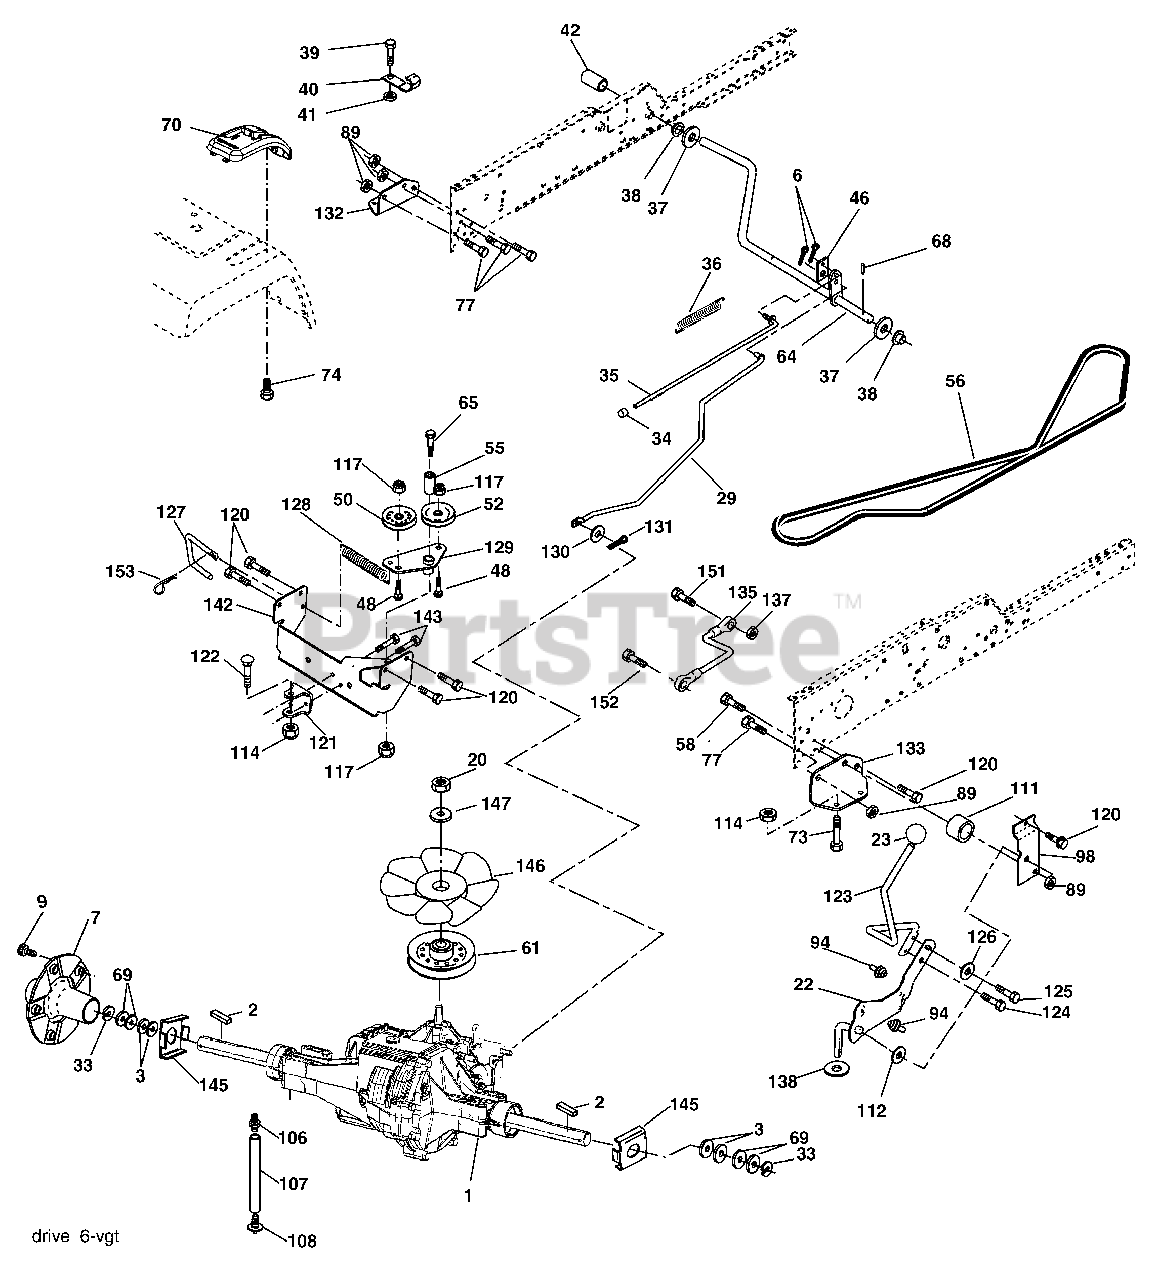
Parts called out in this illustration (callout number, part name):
2	Key Sq. 1/4 x 2.5
3	Washer Thrust
6	Pin, Cotter
7	Wheel, Hub Assembly
9	Bolt, Hub
20	Nut
22	Lever Asm Shift
23	Knob
29	Brake, Rod
33	Ring E
34	Cap, Parking Brake
35	Rod, Parking Brake
36	Spring, Drive Ground
37	Washer 25/32 x 1-1/4 x 16 Ga.
38	Nyliner
39	Screw, Fin. #10-24 x 1
40	Actuator, Interlock Switch
41	Nut Centerlock 10-24 Unc
42	Cover, Pedal
46	Retainer, Spring
48	Bolt Carr. Shoulder 3/8-16 x 1-3/4 Gr. 5
50	Pulley, Idler, Flat
52	Pulley, Idler, Grooved
55	Bearing, Idler
56	V-Belt
58	Bolt Fin Hex 7/16-14 x 1-1/2
61	Pulley, Transaxle
64	Shaft, Brake Pedal
65	Bolt, Shoulder
68	Pin, Roll
69	Washer
70	Console Shift
73	Bolt Hex Flghd 5/16-18 x 3 Gr5
74	Screw Hex Wsh. Hi-Lo 1/4-1/2
77	Bolt Fin Hex 7/16-14 x 1
89	Nut Crownlock 7/16-14 Unc
94	Fastener Christmas Tree
98	Bracket Shift
106	Cap Asm Vent Hydro Gear
107	Line Fuel Hydro 15" VGT
108	O-Ring Asm Hydro Gear
111	Spacer Shift Lever VGTH
112	Washer Nylon High Temp
114	Nut Lock Hex W/Ins 5/16-18 Unc
117	Nut, Lock Flg. 3/8-16
120	Screw 3/8-16 x .75
121	Bracket Strap Torque
122	Bolt 5/16-18 x 2.50
123	Rod Shift
124	Bolt Shoulder 5/16-18 x .561
125	Screw 5/16-18 x 5/8
126	Washer SRRTD 5/16 ID x 1.0 x .125
127	Link Control Clutch
128	Spring Drive GRND
129	Bracket Asm Idler Tensioning
130	Washer 13/32 x 5/8 x 16 Ga.
131	Pin Cotter 3/32 x 3/4
132	Bracket Mtg Hydro 3500 LH VGT
133	Bracket Mtg Hydro 3500 RH VGT
135	Link Asm Control Hydro 3500
137	Nut Lock 5/16-18 NC Thd.
138	Washer Thrust 5/8 x 1.10 x 1/32
142	Strap Torque HG-3500
143	Screw 5/16-18 x 3/4
145	Washer Axle Flange HG-3000
146	Fan 7" Hydro
147	Washer
151	Bolt Fin Hex 5/16-18 x 7/8
152	Bolt Hex 5/16-18 x 1
153	Spring Retainer
